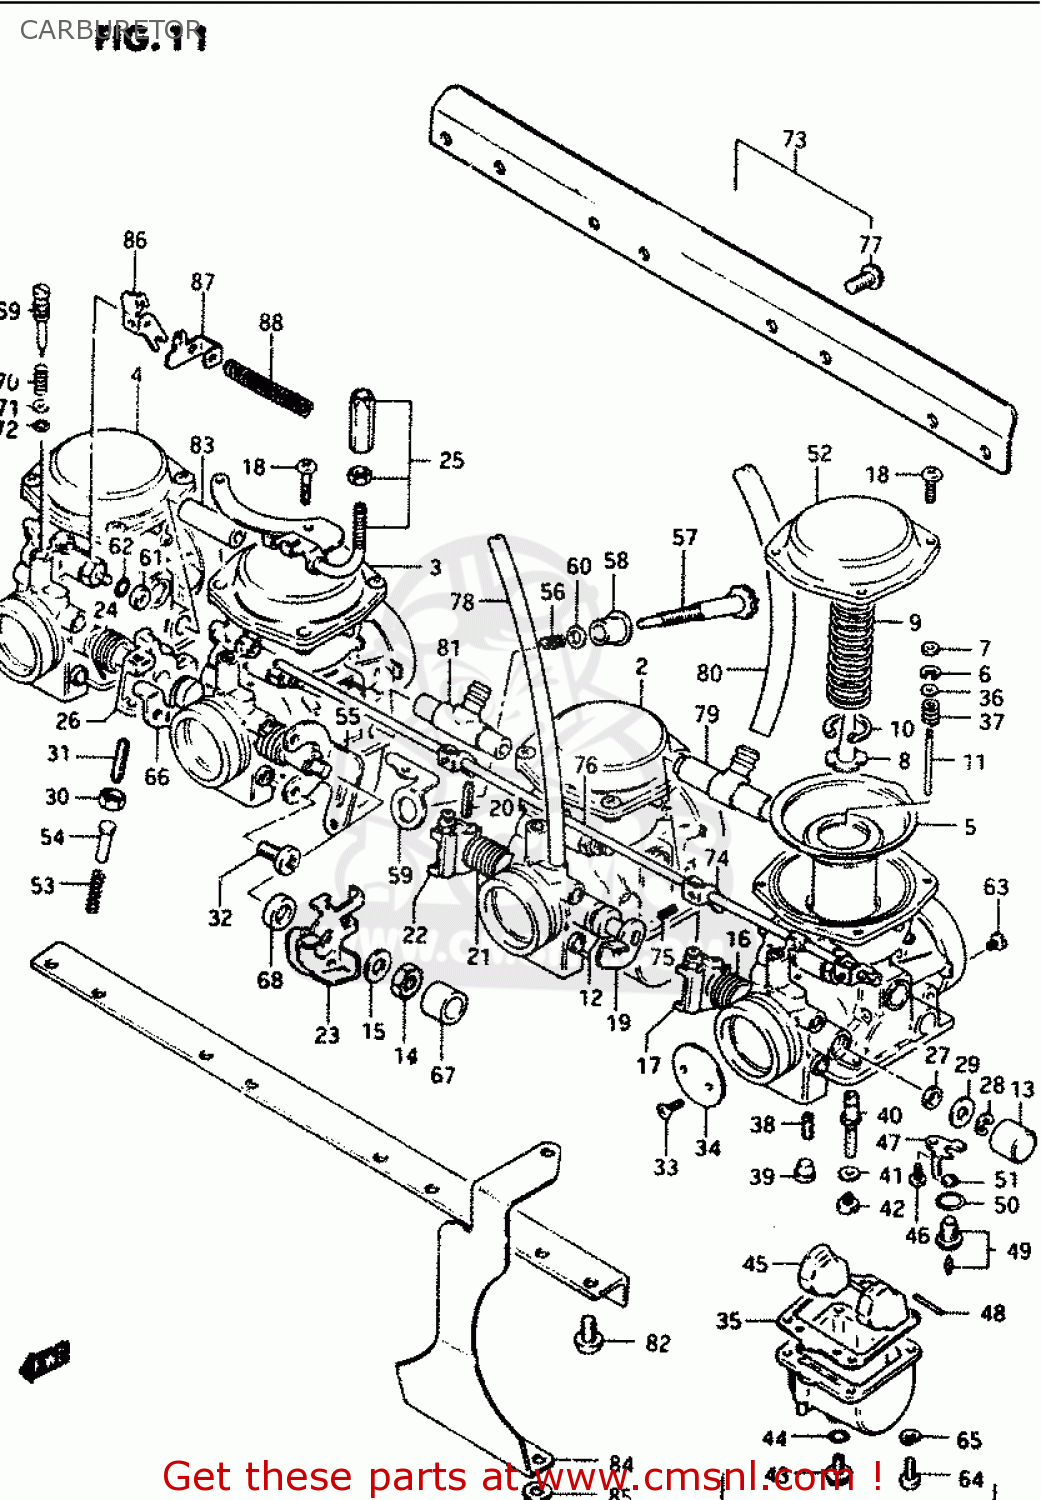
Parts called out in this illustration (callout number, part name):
1	CARBURETOR, LH
2	CARBURETOR, ML
3	CARBURETOR, MR
4	CARBURETOR, RH
5	DIAPHRAGM
6	CLIP,NEEDLE
7	RING
8	HOLDER,GUIDE
9	SPRING
10	E RING
11	NEEDLE,JET
12	GASKET
13	CAP
14	NUT
15	WASHER
16	SPRING,THROTTLE SHAFT
17	SHAFT,THROTTLE
18	SCREW
19	SHAFT,THROTTLE
20	PIN,THROTTLE SHAFT
21	SPRING,THROTTLE SHAFT
22	LEVER,THROTTLE SHAFT
23	LEVER ASSEMBLY,THROTTLE
24	SPRING,THROTTLE SHAFT
25	BRACKET,THROTTLE CABLE
26	SHAFT,THROTTLE
27	SEAL
28	E RING
29	GASKET,THROTTLE SHAFT (NAS)
30	NUT
31	SCREW
32	SCREW
33	SCREW
34	VALVE,THROTTLE
35	GASKET,FLOAT CHAMBER (NAS)
36	WASHER
37	SPRING
38	JET,PILOT
39	PLUG,NEEDLE JET
40	JET, NEEDLE (X-5)
41	WASHER,NEEDLE NOZZLE
42	JET,MAIN(115)
43	PLUG,DRAIN
44	GASKET (NAS)
45	FLOAT
46	SCREW
47	PLATE,NEEDLE VALVE FITING
48	PIN,FLOAT
49	VALVE ASSEMBLY,NEEDLE
50	O RING
51	FILTER
52	COVER,DIAPHRAGM
53	SPRING,THROTTLE SCREW
54	PIN,THROTTLE LEVER
55	BRACKET,THROTTLE ADJUST
56	SPRING
57	SCREW
58	BUSH
59	BRACKET,THROTTLE ADJUST
60	WASHER
61	CAP,STARTER VALVE
62	O RING
63	JET,AIR(150)
64	SCREW
65	LOCK WASHER
66	SHAFT,THROTTLE
67	RING
68	RING
69	SCREW,PILOT AIR
70	SPRING
71	GASKET
72	O-RING
73	CARBURETOR ASSEMBLY
74	LEVER
75	SCREW
76	SHAFT,STARTER
77	SCREW
78	HOSE
79	NIPPLE
80	HOSE,CARBURETOR
81	NIPPLE
82	SCREW
83	NIPPLE
84	CLAMP
85	WASHER
86	PLATE,CHOKE CABLE
87	LEVER,CHOKE CABLE
88	SPRING,CHOKE CABLE
